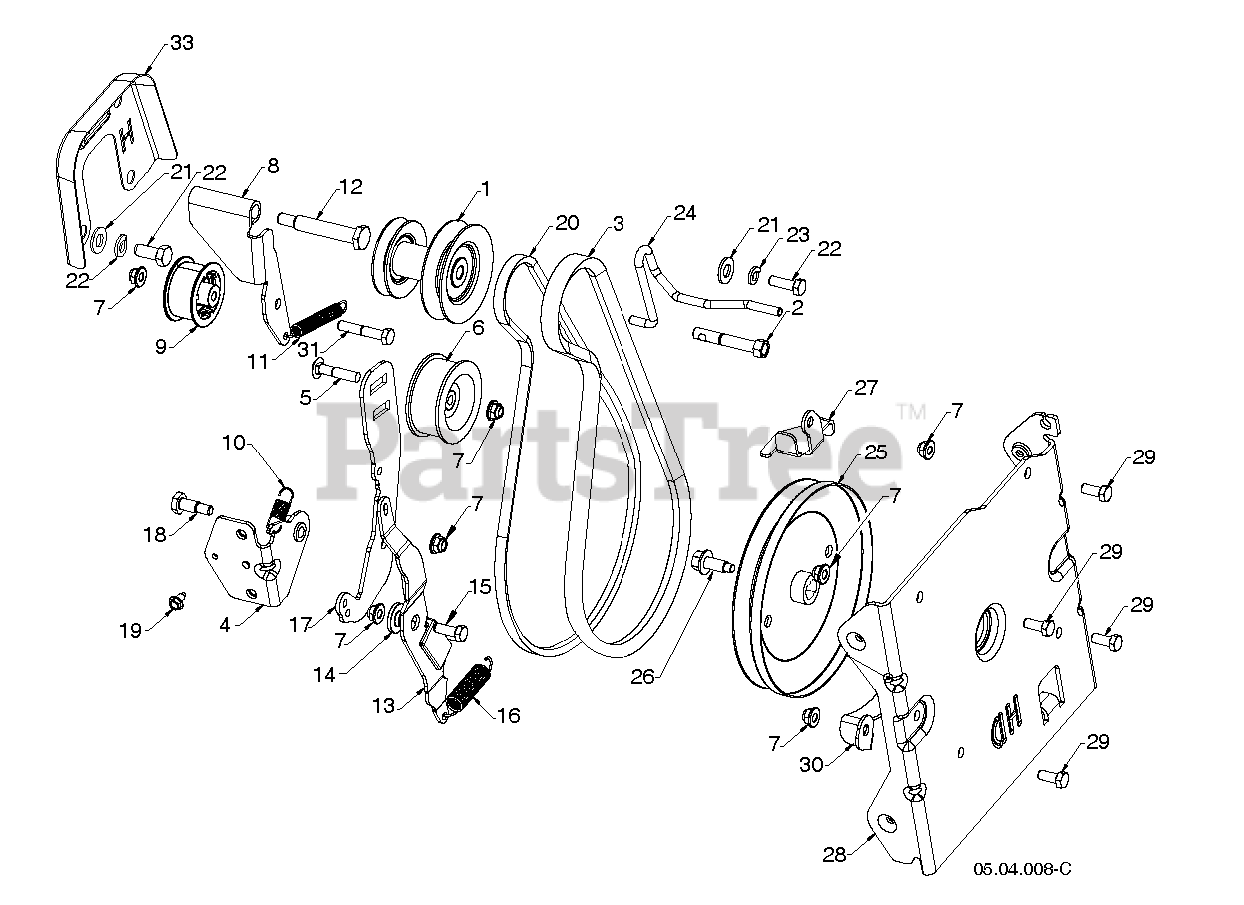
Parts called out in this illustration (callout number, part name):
1	PULLEY WELDMENT
2	BOLT.ENGINE.PULLEY
3	BELT 5L 39.15L
4	BRACKET WELDMENT, IDLER ARM ZI
5	BOLT 5/16-18 CARRIAGE 1.5L
6	PULLEYIDLER.2.0.W/SPACER.CZ
7	NUT HEXAGON FLANGE 5/16-18 ST
8	ARM DRIVE IDLER CLEAR ZINC PLA
9	PULLEYIDLER.2.0.W/SPACER.CZ
10	SPRING IDLER RETURN
11	SPRING RETURN IDLER ARM
12	BOLT 5/16-24X2.25 HEX HEAD SHO
13	ARM IMPELLER BRAKE
14	BUSHING.BRAKE.ARM
15	BOLT HEXAGON BOLT 5/16-18 X 7/
16	SPRING EXTENSION - BRAKE
18	SCREW HEX HEAD SHOULDER
20	BELT 3L 39.68; POLY CORD
21	WASHER 11/32 X 11/16 X 14 GA T
22	SCREW 5/16-24 X .75 GR5
23	WASHER SPRING LOCK WASHER WITH
24	GUIDE.BELT.5L.IMPELLER.3L.DRV
25	PULLEY IMPELLER DD 5L HD
26	SCREW HEXAGON HEAD FLANGE 3/8-
28	BRACKET AUGER HOUSING INTERFAC
29	SCREW HEXAGON HEAD SCREW 5/16-
30	BRACKET.BELT.KEEPER.LOWER.BLAC
31	BOLT, HEX 5/16-18X1-3/4
